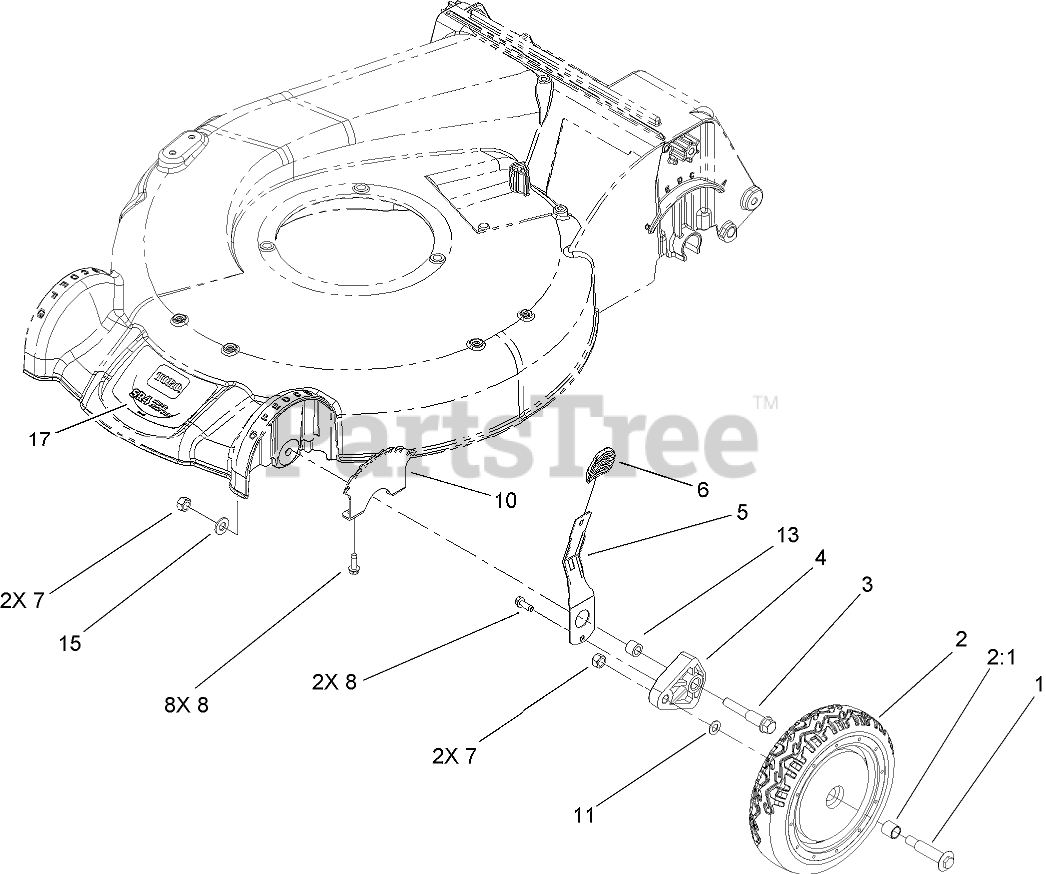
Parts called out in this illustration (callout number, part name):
1	BOLT-SHOULDER
2	WHEEL ASM
2:1	BUSHING
3	SCREW-SHOULDER, HOC
4	ARM-PIVOT
5	ARM-SPRING
6	Knob-Lever, HOC
8	SCREW-HWHTF
10	PLATE-HOC
11	WASHER
13	SPACER-WHEEL
15	WASHER-FLAT
17	DECAL-SUPERCARE
